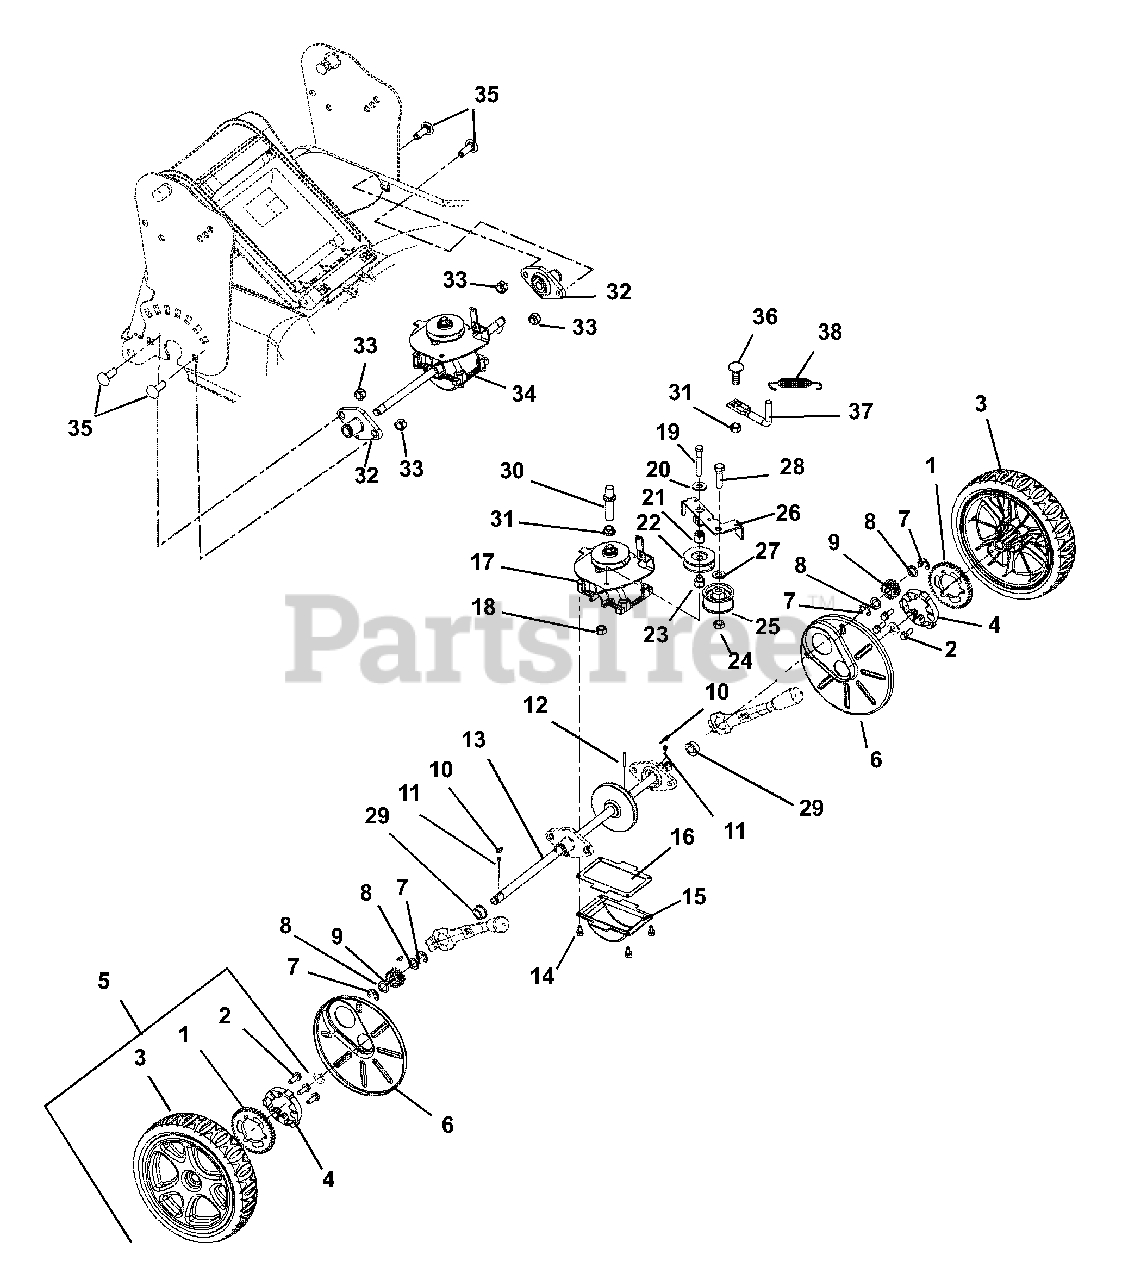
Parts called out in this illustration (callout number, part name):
1	Gear, Wheel
2	Screw, Tapping .25-15 x .75 Hi-LO Hex Washer Head
3	Wheel
4	Ring, Torque
5	Kit, Assembly, LM Rear Wheel
6	Wheel Cover
7	Ring, Retaining External .500 x .042
8	Washer, .500 x .750 x .020 Thrust
9	Pinion, WBLM Drive
10	Key, Woodruff .125 x .50 x .20
11	Spring, .134 x .186 x .144 Compression
12	Pin, Roll .156 x 1.00
13	Shaft, Transmission Output
14	Screw, Tapping 10-24 x .375 Hex Washer Head
15	Sump, Gearbox
16	Gasket, Transmission
17	Kit, WBLM Transmission Housing
18	Nut, Locking Top Flange .25-20
19	Bolt, Hex .25-20 x 2.00 Grade 5
20	Washer, Flat Steel .328 x 1.0 x .094
21	Spacer, .390 x .75 x .189
22	Idler, 3L Front Side .38 x 1.875
23	Spacer, Idler Pulley
24	Nut, Locking Center .38-16
25	Idler, Flat 1.875OD x .75WIDE
26	Arm, Transmission Idler
27	Washer, Flat Steel .406 x .812 x .065
28	Bolt, Hex .38-16 x 1.38 Grade 5
29	Bushing, Transmission Output Shaft
30	Belt, Finger
31	Nut, Locking Flange .250-20
32	Kit, Wheel Mount Hub Service
33	Nut, Locking Top Flange .31-18
34	Kit, Transmission Service
35	Bolt, Round Head Square Neck .31-18 x 1.00 Grade 5
36	Bolt, Round Head Square Neck .25-20 x .50 Grade 5
37	Belt, Finger
38	Spring, Tension .051X.60X2.25
